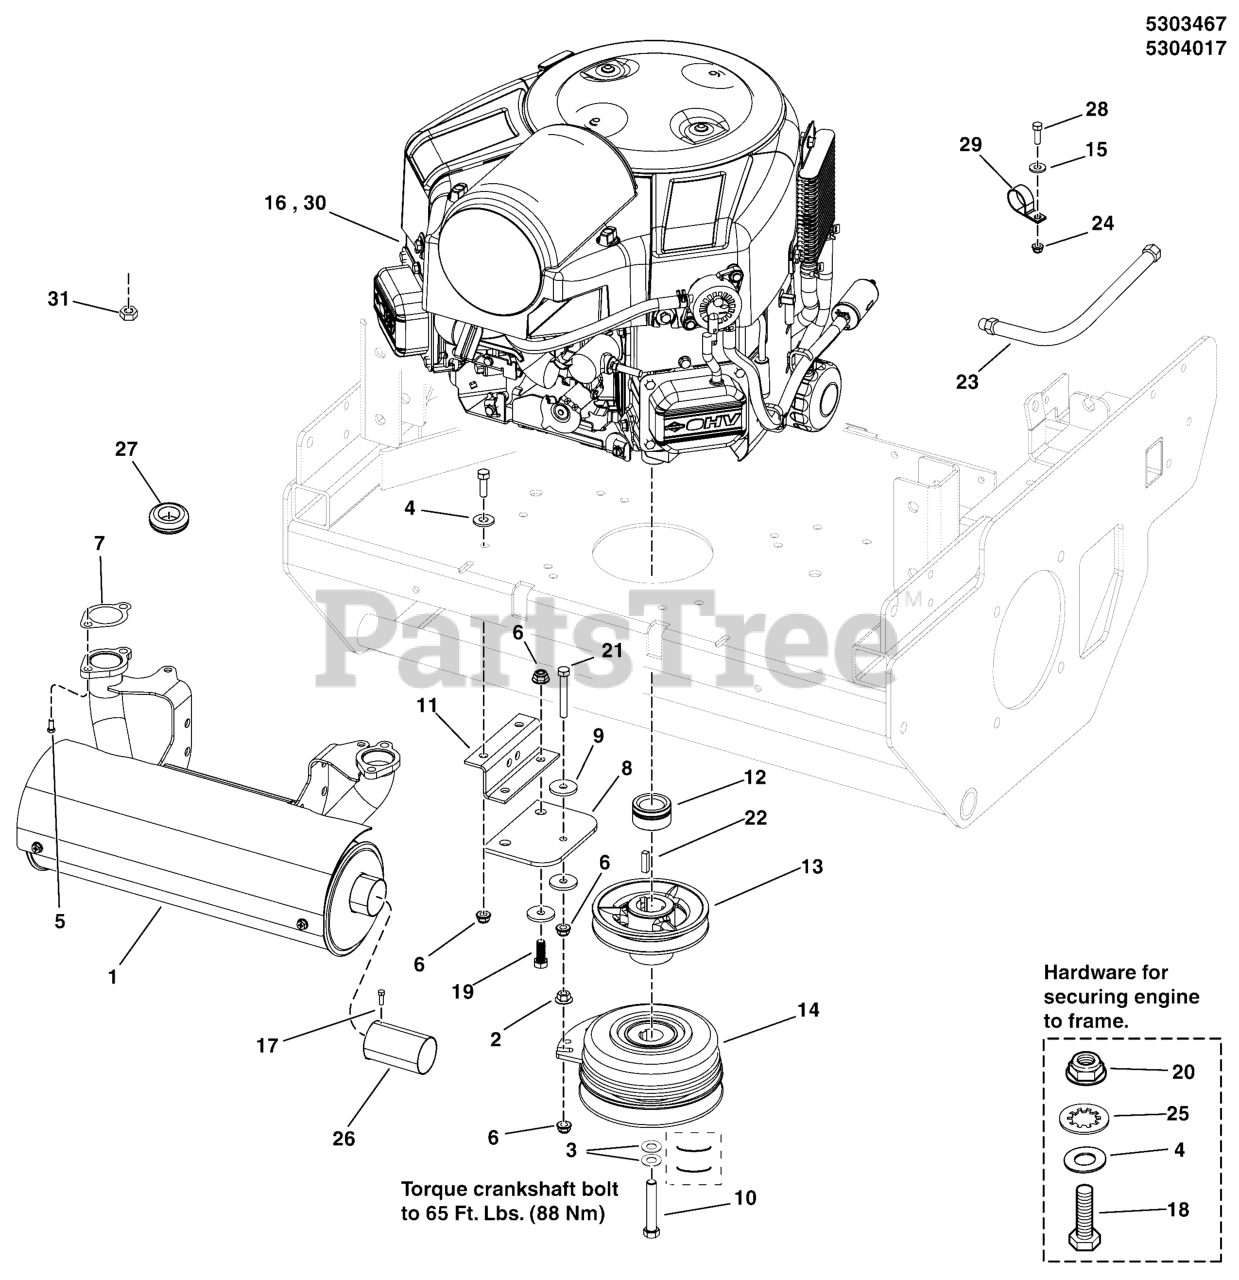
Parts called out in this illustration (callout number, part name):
1	MUFFLER, RIGHT OUTLET ASSY
2	NUT, 5/16-18 HEX SERRATED FLANGE (LARGE)
3	BELLEVILLE WASHER 1.1875 X .442 X .089
4	WASHER, 5/16" SAE
5	SCREW-HEX SEMS LOCK WSHR 5/16-18X0.875
6	NUT, 5/16-18 HEX NYLOCK FLANGE
7	GASKET, EXHAUST
8	CLUTCH ANCHOR PAD
9	WASHER, .34 X 1.25 X 10 GA
10	BOLT, CRANKSHAFT,7/16-20X2-3/4, GD8
11	ANCHOR, CLUTCH - BLK
12	SPACER, 1.13 X 1.75 X 1.35, CZ
13	PULLEY, 4.75 OD X 1-1/8 BORE, BC-48
14	CLUTCH,WARNER,200 'lbs,1.13
15	WASHER, 1/4 SAE
16	ENGINE, 27HP B&S COMM TURF, 1-1/8 X 4.29
17	SCREW,SELF-TAP,#8-32 X 3/8,WASH HEX, CZ
18	BOLT, 5/16-24 X 1-3/4, GD8, PHOS
19	BOLT, 5/16-18 X 1 GD5 CZ
20	NUT, 5/16-24, TOP LOCK FLANGE, GD8 PHOS
21	BOLT, 5/16-18 X 2-1/4 TFL, GD5 YZ
22	KEY, 1/4 SQ X 1-1/4
23	HOSE, OIL DRAIN
24	NUT, 1/4-20 HEX SERR. FLANGE
25	WASHER, 5/16 INT. TOOTH LOCK
26	EXTENSION, TAILPIPE, 3", BLACK
27	GROMMET, 7/8"ID, 1/4" THICK STK
28	HHCS, 1/4-20 X 0.625, GR5, ZINC/CLEAR
29	CLAMP, VINYL INSULATED, 1.00
30	ENGINE, 26HP, B&S, VANGUARD
31	NUT, 5/16-24 JAM
